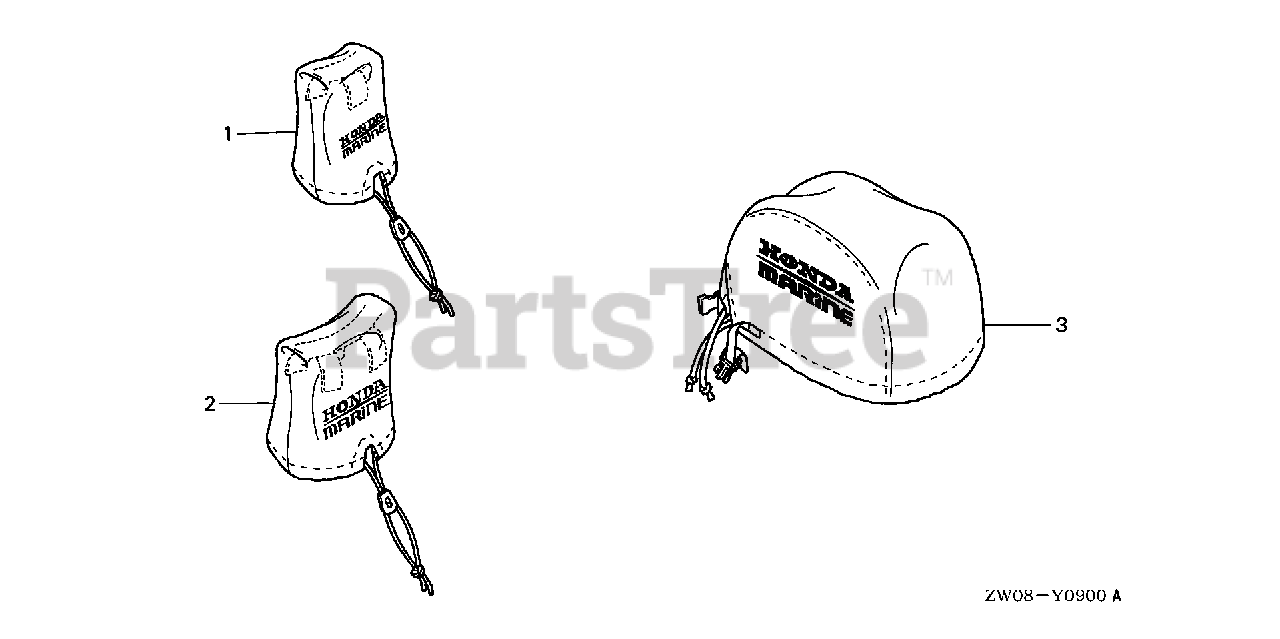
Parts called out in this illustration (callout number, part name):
1	COVER KIT, REMOTE CONTROL BOX
2	COVER KIT, REMOTE CONTROL BOX (TOP MOUNT DUAL)
3	COVER KIT, ENGINE (BF75/90)
